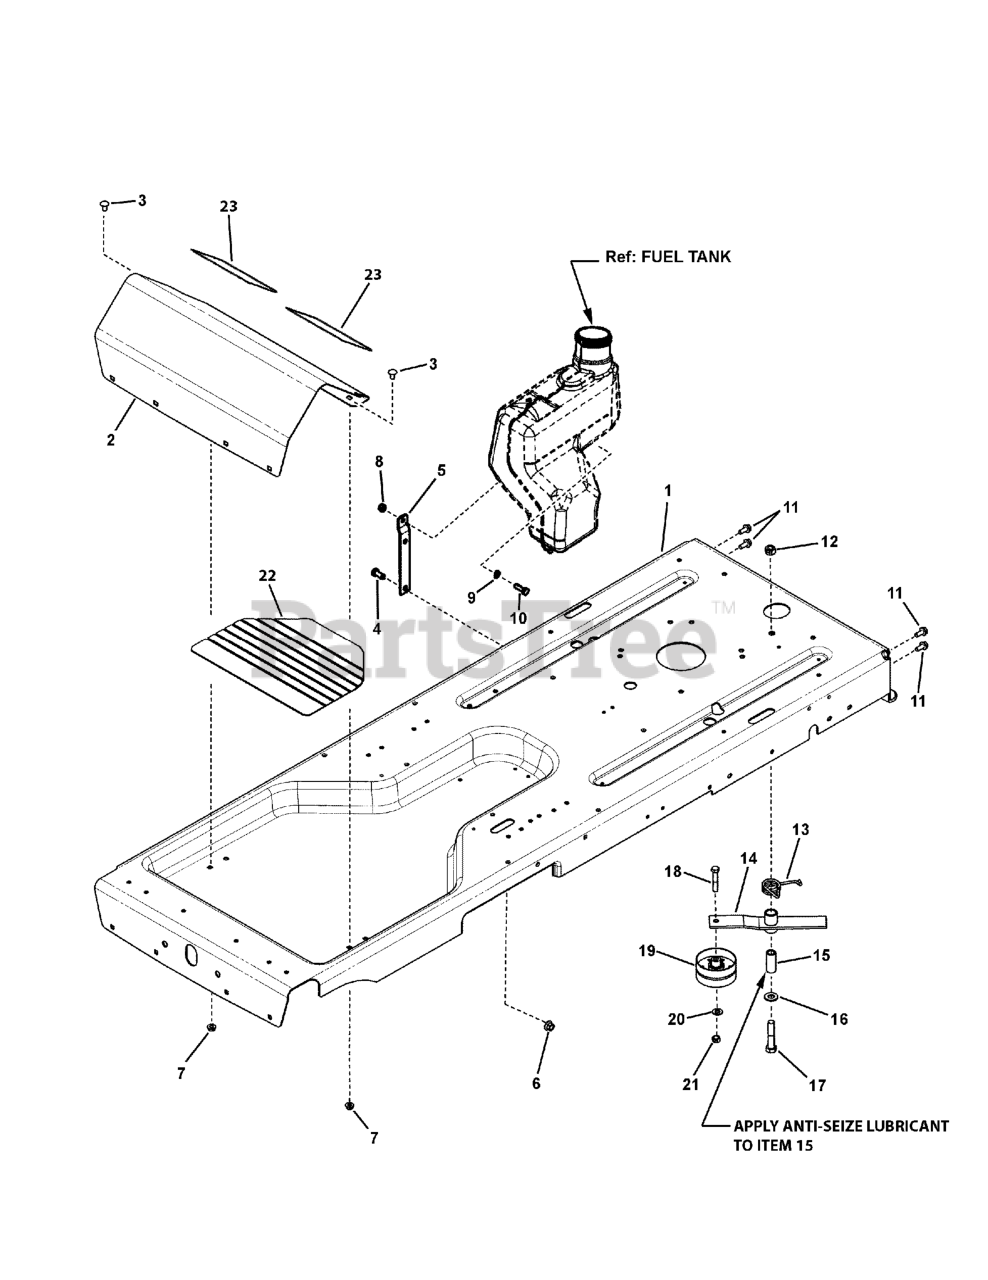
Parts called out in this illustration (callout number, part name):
1	FRAME, RZT
3	BOLT, 5/16-18 x 5/8" Round Head Short Square Neck Carriage, GR 5
4	SCREW, 3/8-16 x 3/4" Hex Head Cap, GR 5 ZP
5	BRACKET, Support, Fuel Tank
6	NUT, 3/8-16 Hex Flange lock, GR F, BZ
7	NUT, 5/16-18, Hex Flange Lock, GR 5
8	NUT, 5/16-18- Nyloc, YZ
9	WASHER, .34 x .62 x 16 Ga, Flat
10	SCREW, 5/16-18 x 1" Hex Head Cap, GR 5, YZ
11	SCREW, 5/16-18 x 3/4" Hex Washer Self-Tap, YZ
12	NUT, 1/2-13 Hex Center Lock, GR 5, YZ
13	SPRING, Torsion, RH Wind
14	WELDMENT, Hydro Idler MY08
15	SPACER, Hydro Idler
16	WASHER, .531 x 1.062 x .121, Flat, YZ (SAE)
17	SCREW, 1/2-13 x 2-1/2", Hex Head Cap, GR 5 (Black Phosphate)
18	SCREW, 3/8-16 x 2" Hex Head Cap, GR 5, YZ
19	IDLER, 3.25" OD x .391 ID x 1.63, Backside
20	WASHER, 3/8" Flat (SAE)
21	NUT, 3/8-16 Hex Center Lock, YZ
22	MAT, Floor Pan, RZT
23	FOOT PAD, Wide
